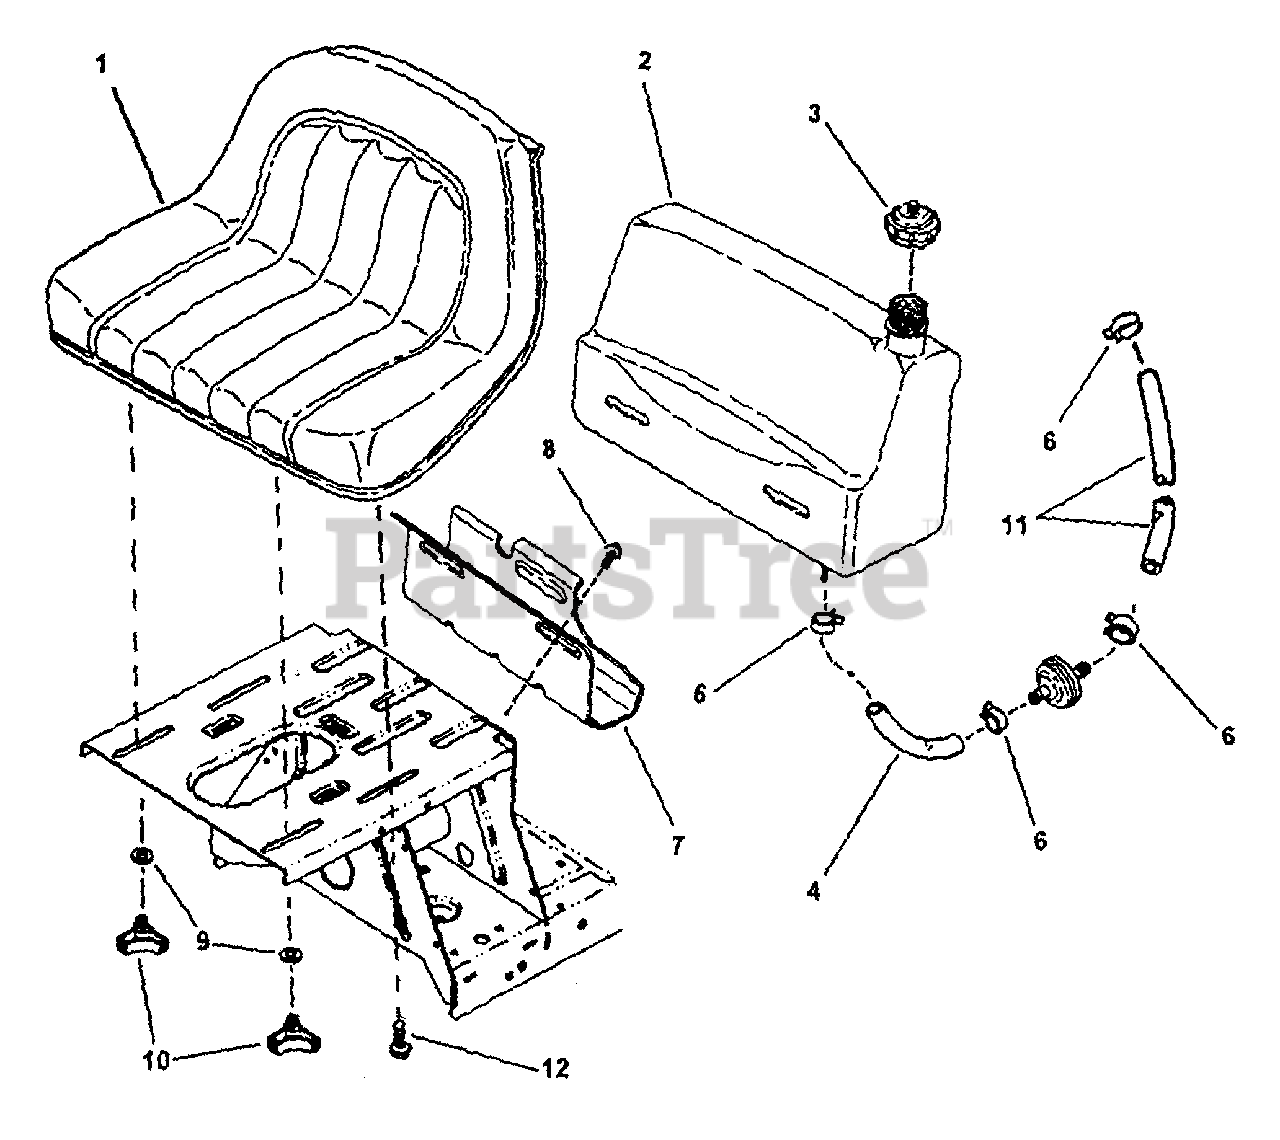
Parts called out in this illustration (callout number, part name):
1	SEAT, Operator
2	ASSEMBLY, Fuel Tank
3	CAP, Fuel Tank
4	HOSE, Fuel (8-1/2" Long)
6	CLAMP, Fuel Line
7	BRACKET, Fuel Tank (Rear)
8	SCREW, 5/16-18 x 1/2" Pan Head Self-Tap
9	SPACER, 21/64"
10	KNOB, 3-Prong Seat
11	HOSE, Fuel (3-1/2" Long)
12	BOLT, 5/16-18 x 1/2" Hex Flange Lock
